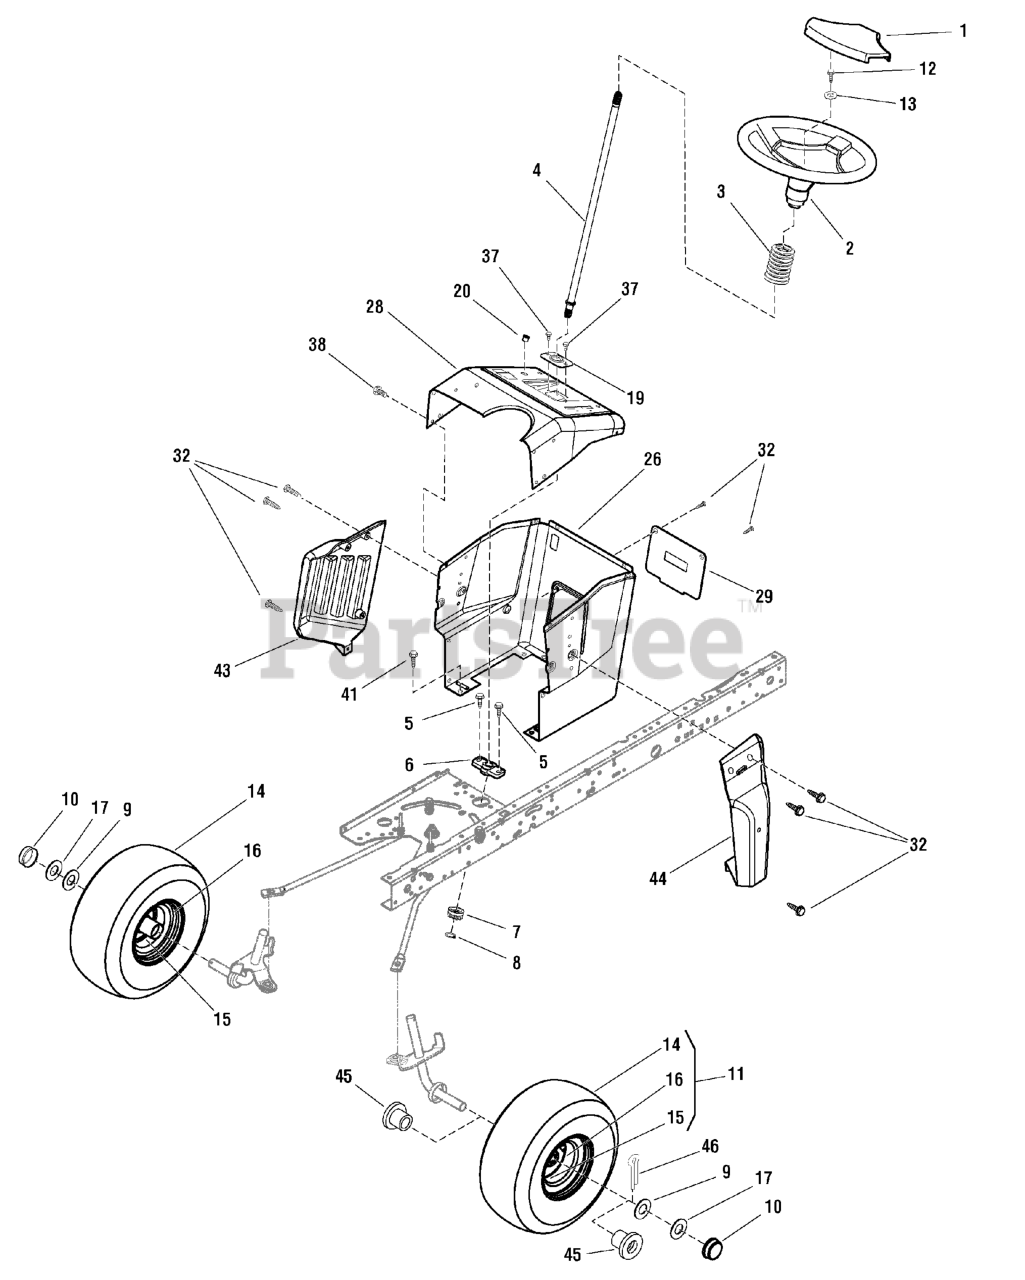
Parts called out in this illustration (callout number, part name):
1	COVER, Integra
2	STEERING WHEEL
3	BELLOWS
4	SHAFT, Steering
5	SCREW, 5/16-18
6	BEARING, Lower
7	GEAR, Pinion
8	SNAP RING, 1/2
9	WASHER, Flat 1-3/4
10	HUB CAP
11	WHEEL & TIRE ASSY, 15X6.0-6
12	SCREW, Thread Forming, 1/4-20 x 1
13	WASHER, Flat
14	TIRE, 15 x 6 2 Ply K358
15	FITTING, Grease
16	VALVE STEM, TR412
17	WASHER, Flat, 1-1/4
19	BEARING, Steering
20	GROMMET, Parking Brake
26	SUPPORT, Dash (Black)
26	SUPPORT, Dash (Grey)
28	DASH, Twin (Black)
28	DASH, Twin (Grey)
29	PANEL, Access (Black)
29	PANEL, Access (Grey)
32	SCREW, Thread Forming
37	SCREW, 1/4" AB x 1/2
38	SCREW, Self Tap, #8 x 3/8
41	CAPSCREW, 5/16-18 x 3/4
43	PANEL, Side, Right
44	PANEL, Side, Left
45	BEARING, Wheel
46	PIN, Cotter, 3/4
